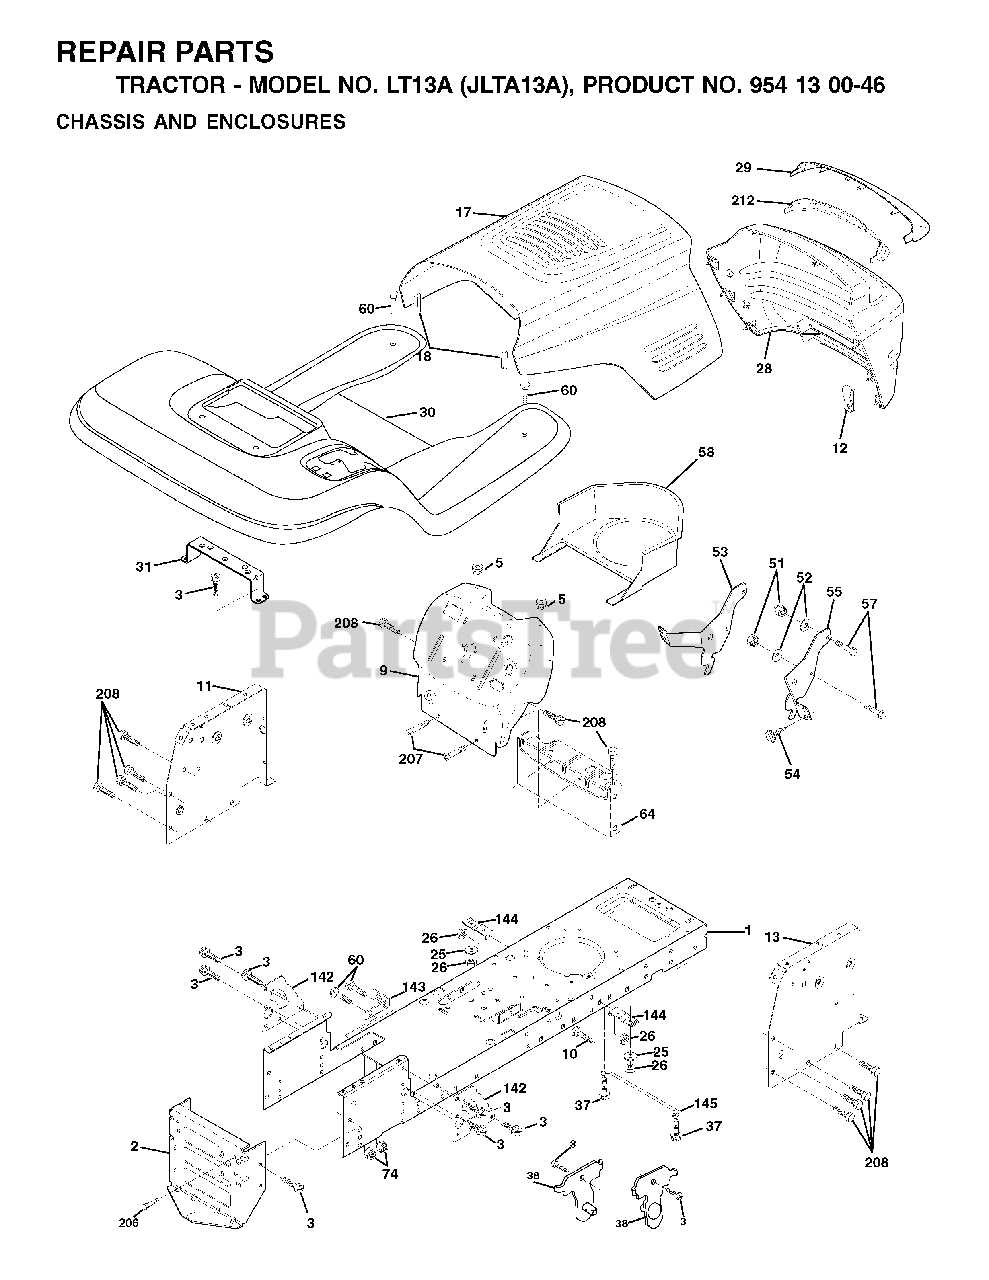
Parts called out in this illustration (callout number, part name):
2	DRAWBAR
3	SCREW 3/8-16X3/4
5	BUMPER.RUBBER.HOOD
10	BOLT D
11	PANEL DASH LH
13	PANEL DASH RH
18	BUMPER HOOD T
25	WASHER
26	NUT
38	BRACKET
51	LOCKNUT
57	BOLT
58	AIR DUCT P/L/LT
64	DASH LOWER
74	LOCKNUT
142	PLATE
143	BRACKET, SWAY BAR
144	BRACKET FOOTREST
145	ROD PIVOT CHASSIS/HOOD
206	SHOULDER BOLT 5/16-18TT
207	SCREW, 5/16-18 X 1/2
208	SCREW 3/8-16X1/2
